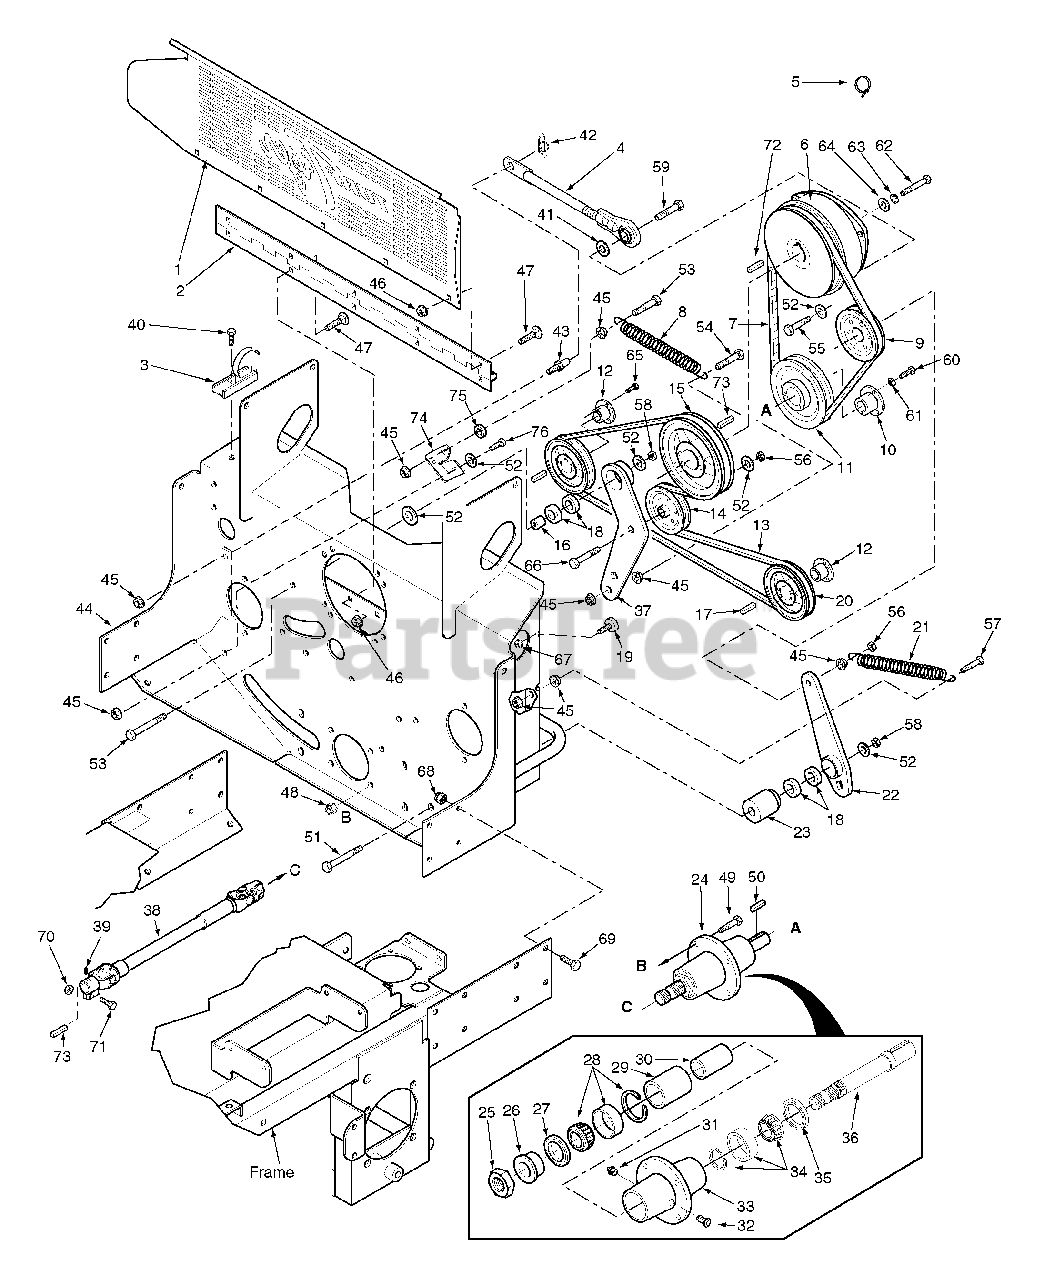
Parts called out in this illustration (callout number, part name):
1	Belt Guard, Rear
2	Hinge, Belt Guard
3	Latch, Hood
4	Rod Assembly, Clutch Anti-Rotation
5	Clamp, Cable
6	Clutch, Ogura GT-3.5
7	Belt, Deck Drive
8	Spring, Transmission Idler
9	Pulley, Idler 5" Dia.
10	Tapered Hub, 1" Bore
11	Pulley, 6.70 Tapered Bore
12	Tapered Hub, 17mm Bore
13	Belt, Pump Drive STT
14	Pulley, Idler 4" Dia.
15	Pulley, 4.55 Dia.-1.125 Bore
16	Spacer, Idler Bearing
17	Key, 5.0 x 5.0 x 25mm
18	Ball Bearing
19	Bumper, Rubber
20	Pulley,
21	Spring, PTO
22	Idler Arm Weldment, PTO Drive
23	Pivot, Idler PTO
24	Spindle Assembly, Deck Drive
25	Nut, 1.06-18 Thread
26	Spindle Bushing, Bottom
27	Seal, 2.0 OD x 1.625 Bore
28	Roller Bearing Tapered
29	Spacer, Outside
30	Spacer, Inside
31	Grease Fitting, 1/4-28
32	Relief Fitting
33	Spindle Housing
34	Roller Bearing Tapered
35	Seal, 2.0 OD x 1.5 Bore
36	Shaft, Deck Drive
37	Idler Arm Weldment, Pump Drive
38	Driveshaft (Air Cooled Engine)
39	Set Screw, 3/8-16 x 3/4" Torx Socket
40	Screw, #10-32 x .56
41	Flatwasher, 3/8-.391 x .938 x .105
42	Pin, Rue Cotter 3/8 Dia.
43	Stud, Anti Rotation
44	Pump Mounting Plate Weldment (Air Cooled)
45	Nut, Serrated Flange 3/8-16
46	Nut, Serrated Flange 1/4-20
47	Bolt, Carriage 1/4-20 x 1/2"
48	Nut, Elastic Stop 5/16-18 Grade 8
49	Bolt, Hex Head 5/16-18 x 1-3/4" Grade 8
50	Key, 1/4 x 1/4 x 1-1/2"
51	Bolt, Hex Head 3/8-16 x 4-1/2" Grade 8 Black
52	Washer, 3/8 Hardened
53	Bolt, Hex Head 3/8-16 x 1-3/4" Grade 8 Black
54	Bolt, Hex Head 3/8-16 x 1-1/2" Grade 8 Black
55	Bolt, Hex Head 3/8-16 x 2-1/2" 1.5 Thread Grd.8
56	Nut, Center Lock 3/8-16
57	Bolt, Hex Head 3/8-16 x 1-1/2" Grade 8 Black
58	Nut, Elastic Stop 3/8-16
59	Bolt, Hex Head 3/8-16 x 2"
60	Bolt, Hex Head 1/4-20 x 1-3/8"
61	Lockwasher, 1/4 Spring
62	Bolt, Hex Head 7/16-20 x 2-1/2" UNF
63	Lockwasher, 7/16 Spring
64	Flatwasher, 7/16-.469 x 1.75 x .25
65	Bolt, Hex Head 1/4-20 x 1" Grade 8
66	Bolt, Hex Head 3/8-16 x 1-3/4"
67	Nut, Serrated Flange 5/16-18
68	Nut, Elastic Stop 3/8-16
69	Bolt, Hex Head 3/8-16 x 1"
70	Nut, Center Lock 3/8-16
71	Bolt, Hex Head 3/8-16 x 1-3/4"
72	Key, 1/4 x 1/4 x 2-1/4"
73	Key, 1/4 x 1/4 x 1"
74	Bracket
75	Spacer
76	Bolt, Hex Head 3/8-16 x 1"
